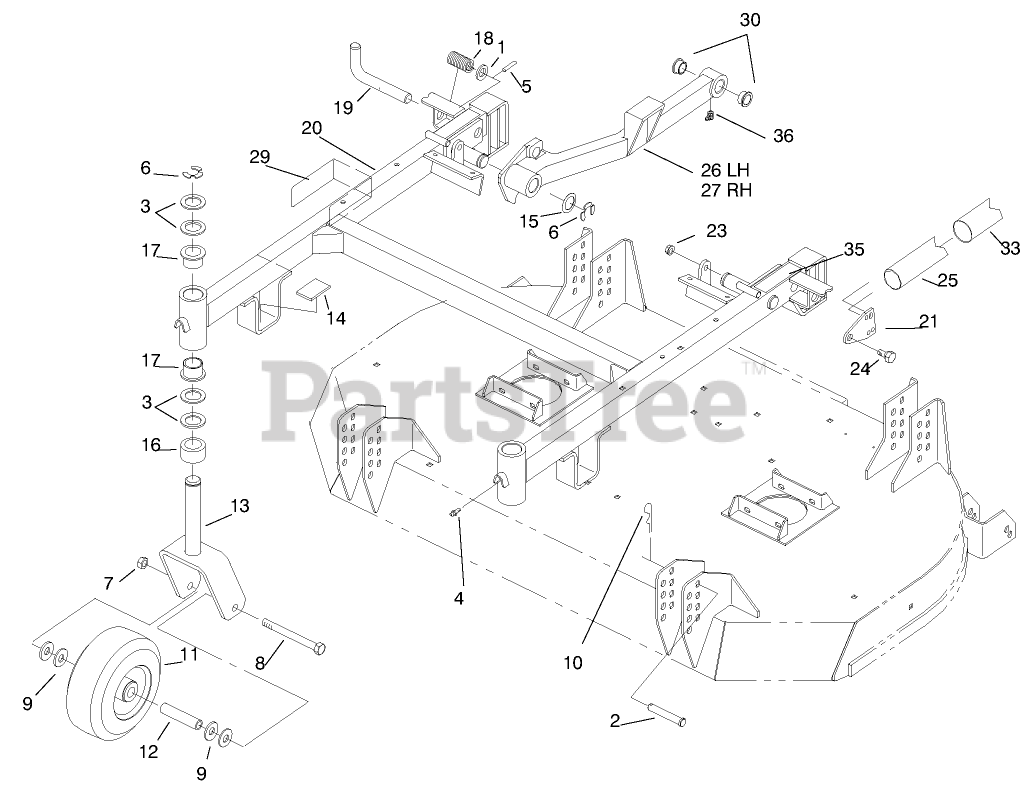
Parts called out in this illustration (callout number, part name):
1	Washer
2	PIN-CLEVIS
3	WASHER-THRUST
4	FITTING-GREASE
5	PIN-ROLL
6	RING-RETAINING
7	NUT-HEX
8	SCREW-HH
9	WASHER-FLAT
10	PIN-HAIR
11	CASTOR WHEEL ASM
12	SPANNER-TIRE
13	Castor Fork
14	CUSHION - RUBBER
15	Washer
16	SPACER-CASTOR
17	BUSHING
18	SPRING-COMPRESSION
19	PIN - PIVOT
20	Frame-Carrier
21	PLATE-END, SPRING
23	NUT-LOCK, NI
24	BOLT-SHOULDER
25	SPRING-EXTENSION
26	LH PUSH ARM / BUSHING
27	RH PUSH ARM / BUSHING
29	DECAL - HOC CE-OBS
30	BEARING-FLANGE
33	COVER-SPRING
35	DECAL-WARNING
36	FITTING-GREASE
